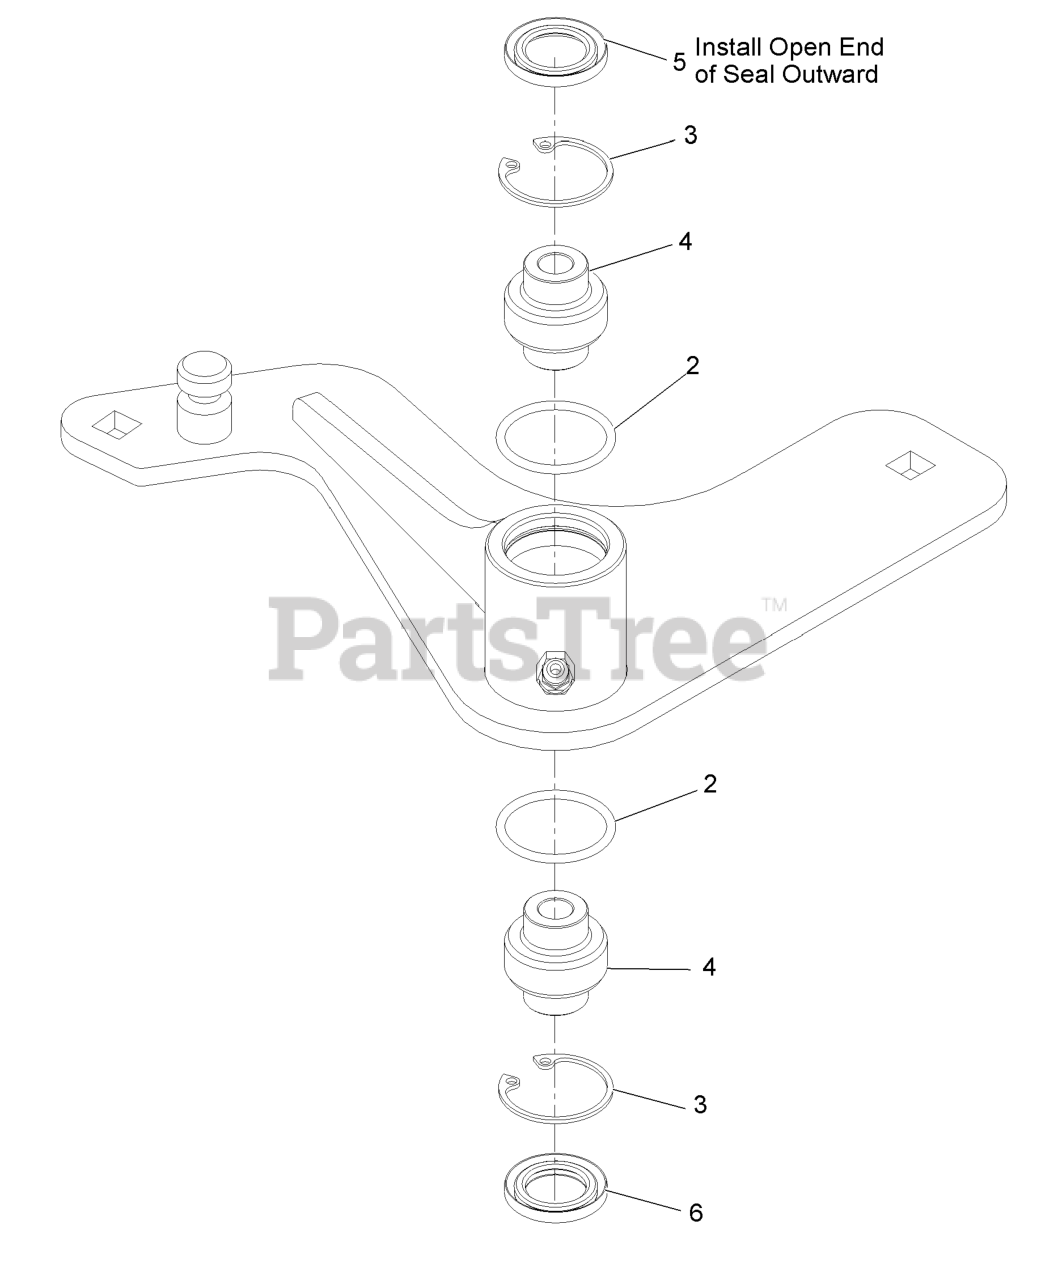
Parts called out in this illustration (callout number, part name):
3	Ring-Retaining
4	Bearing-Spherical
5	Seal-Single Lip
6	Seal-Double Lip
